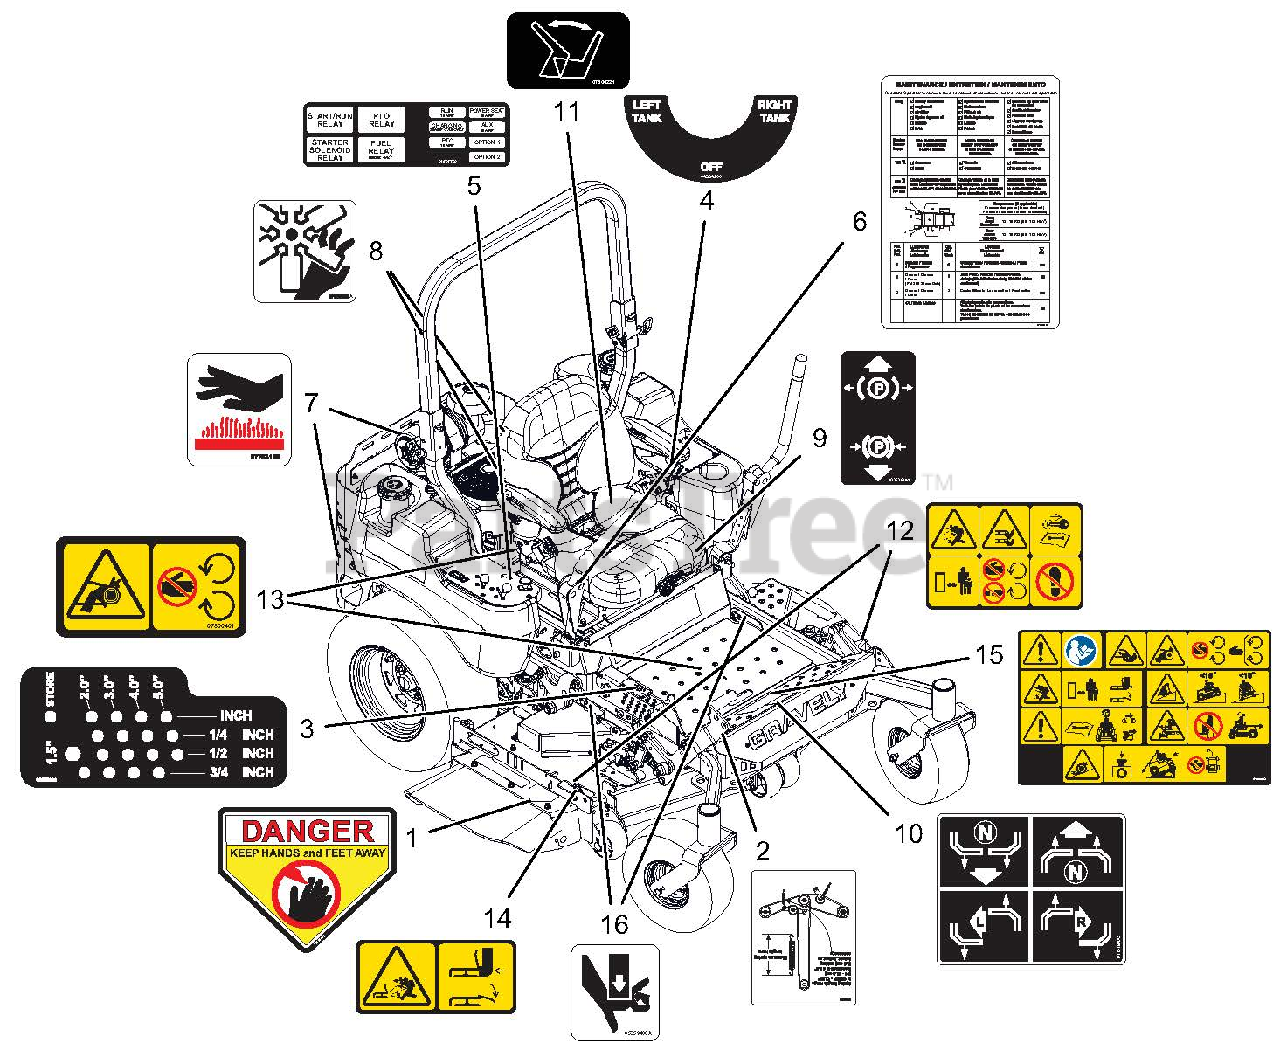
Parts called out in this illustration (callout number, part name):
1	DECAL, DANGER
2	DECAL, BELT ROUTING
3	DECAL, HEIGHT OF CUT
4	DECAL, FUEL VALVE
5	DECAL, FUSE BOX
6	DECAL, MAINTENANCE
7	DECAL, HOT SURFACE
8	DECAL, DANGER FAN
9	DECAL, PARKING BRAKE LEVER
10	DECAL, INSTRUCTIONAL-STEERING
11	DECAL - SEAT RELEASE
12	DECAL, SAFETY - MOWER DECK
13	DECAL, SAFETY - GUARDING
14	DECAL, SAFETY - DECK GUARDING
15	DECAL, MAIN SAFETY
16	DECAL, PINCH POINT
